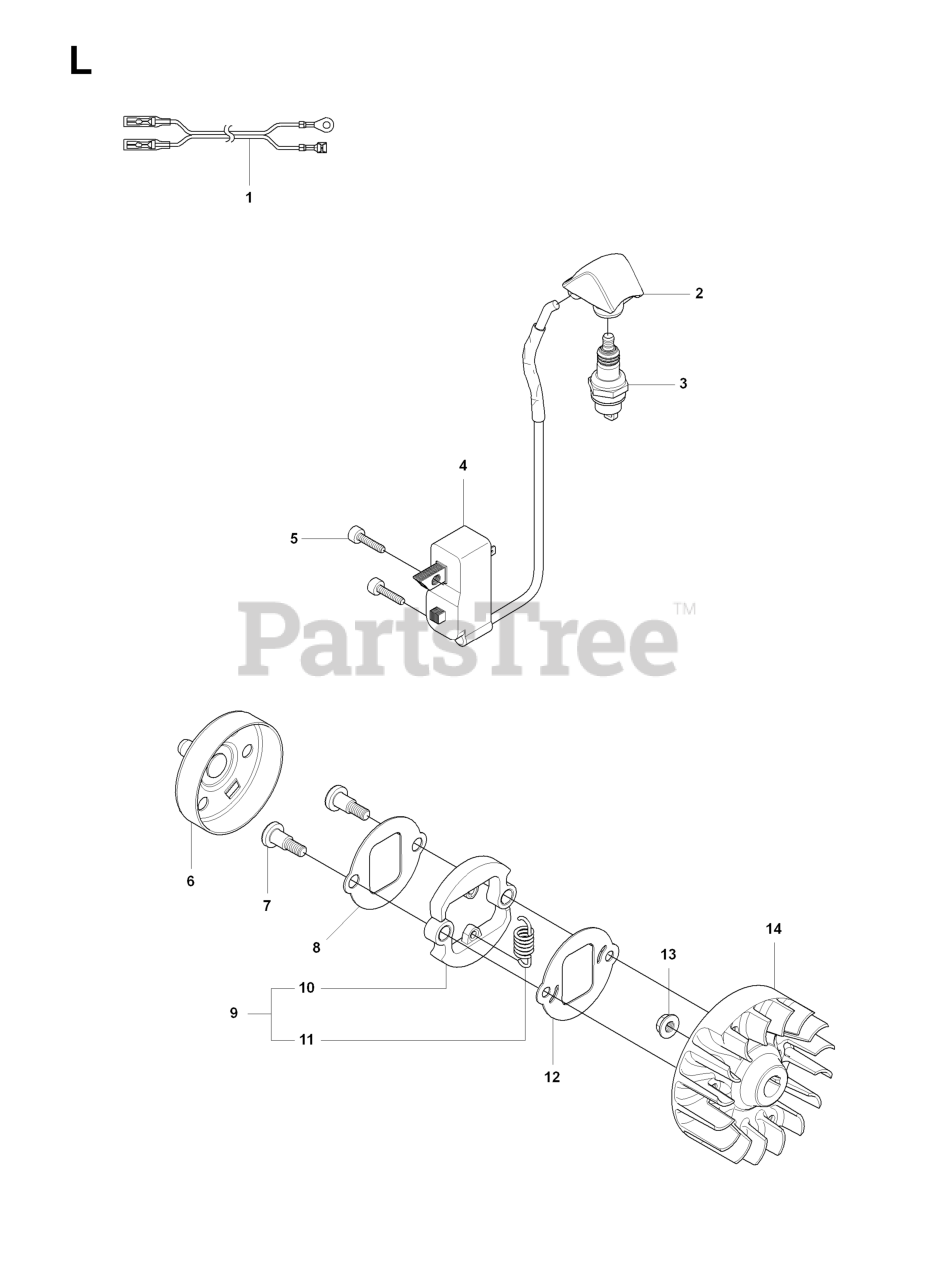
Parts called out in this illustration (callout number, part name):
1	SHORT CIRCUIT CABLE
2	SPARK PLUG CAP
3	SPARK PLUG RCJ6Y NLA
4	IGNITION MODULE
6	CLUTCH DRUM
8	WASHER, CLUTCH
13	FLANGE NUT
